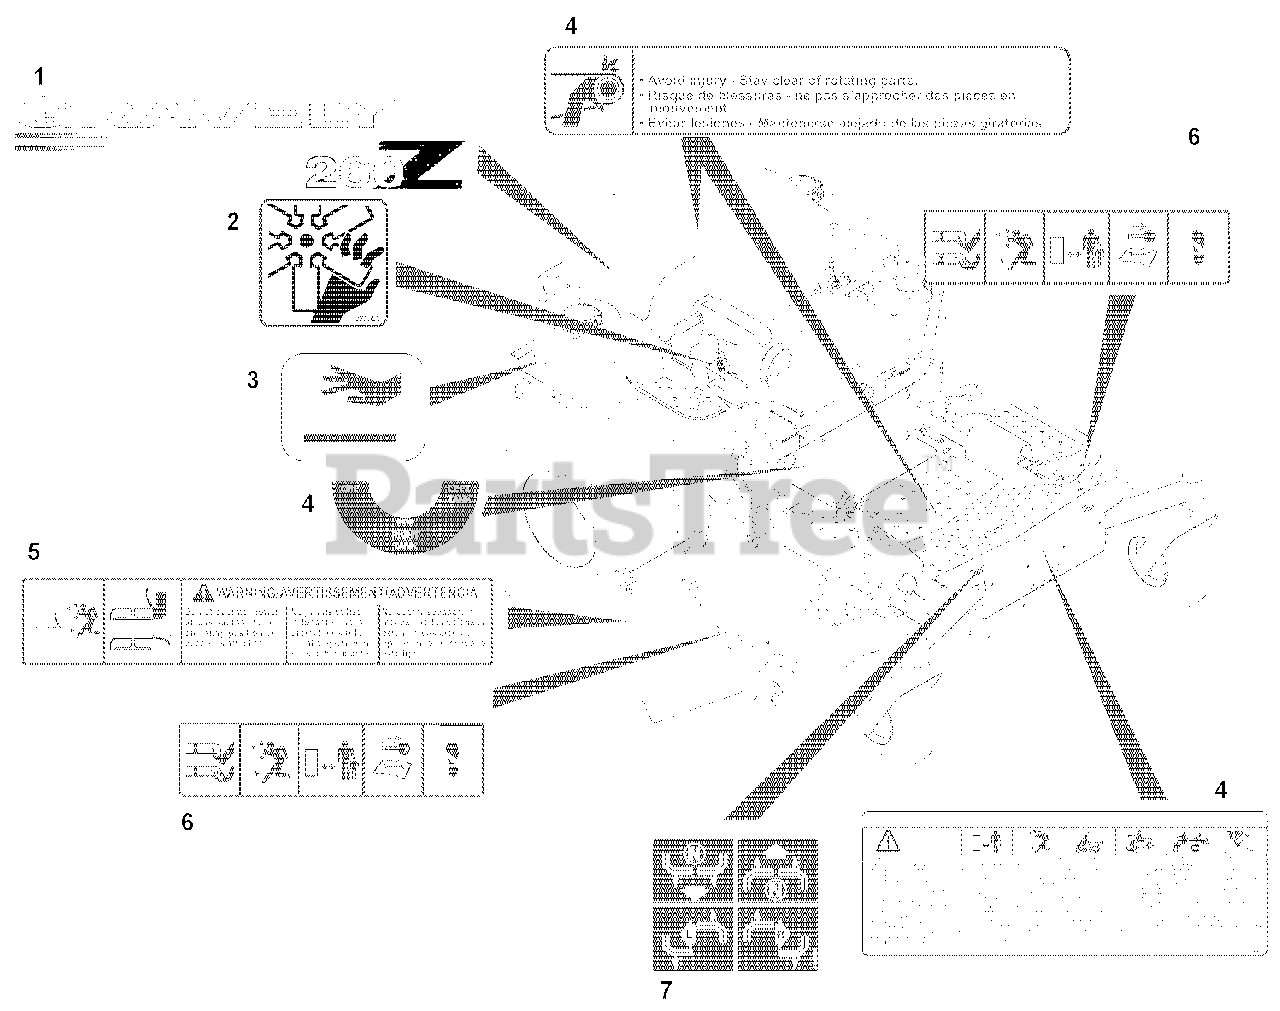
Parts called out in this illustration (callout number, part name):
1	Decal, PM-260Z Hood (046, 047, 067, 068, 085, 088, 089, 105, 106)
2	Decal, Danger Fan
3	Decal-Hot Surface
4	Set, Decal-Common Danger/Fuel
5	Decal, Warning
6	Decal, Mower Pan Head Danger
7	Decal-Instructional
